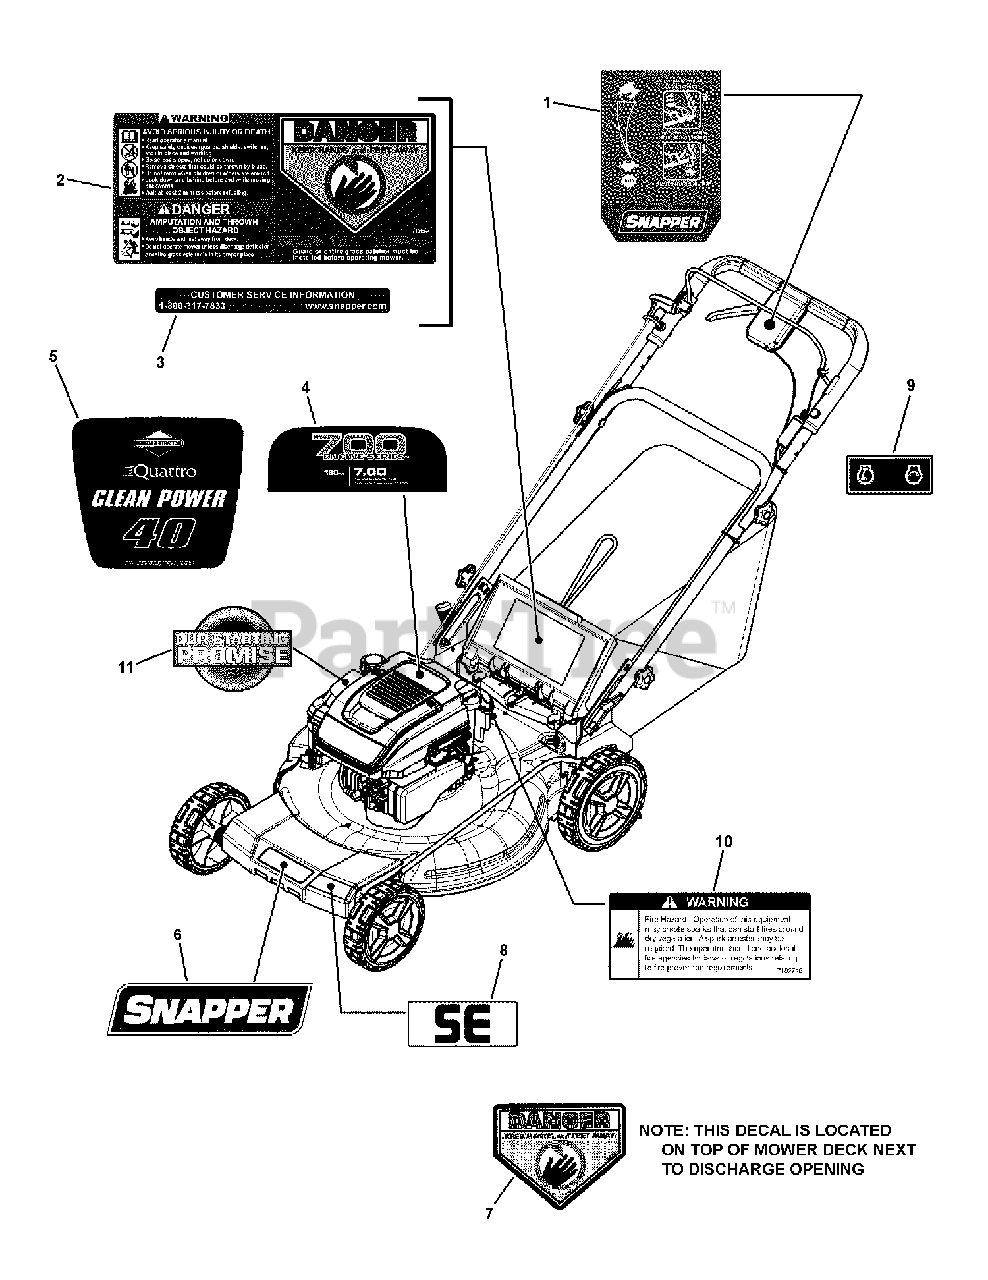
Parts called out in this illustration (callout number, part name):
1	DECAL, Control Head, Variable Speed, Snapper
2	DECAL, Warning, Rear Discharge Door
3	DECAL, Customer Service, MY08, Snapper
4	DECAL, Briggs Engine, 700 Series
5	DECAL, Briggs Engine, Snapper
6	DECAL, Front Shroud, Snapper Logo
7	DECAL, Danger, Cut Finger
8	DECAL, Front Cover "SE"
9	DECAL, Ignition
10	DECAL, Spark Arrestor
11	DECAL, Starting Promise
